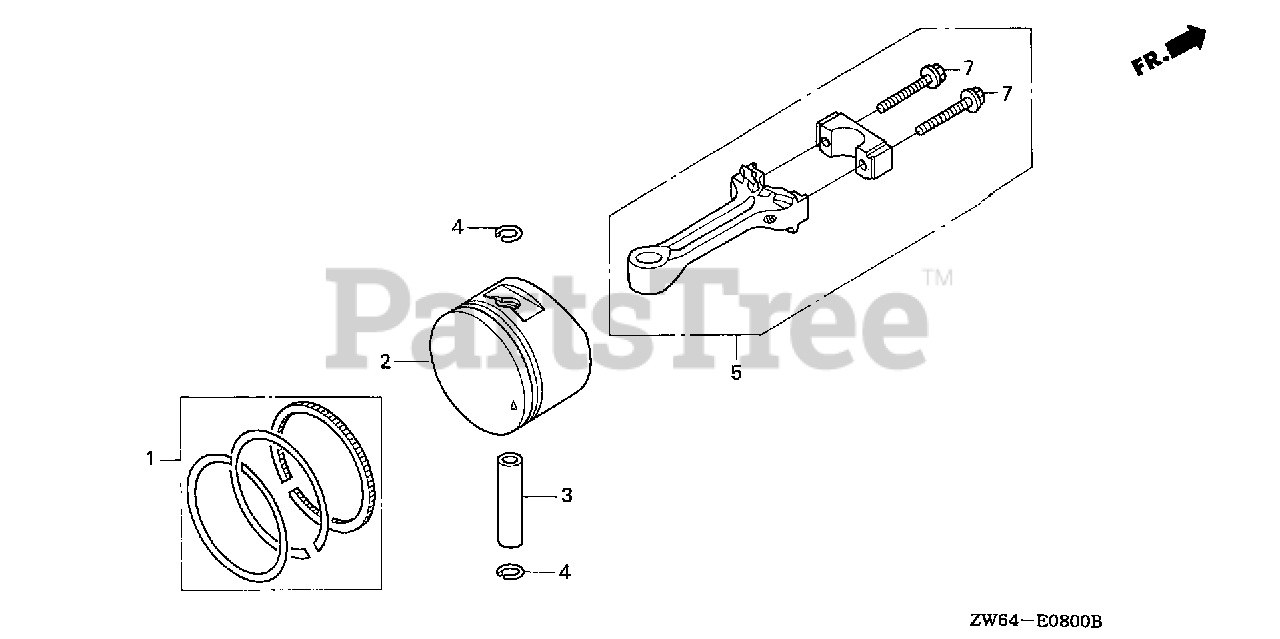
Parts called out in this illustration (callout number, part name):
1	RING SET, PISTON (STD)
2	PISTON (STD)
3	PIN, PISTON
4	CLIP, PISTON PIN (10MM)
5	ROD ASSY., CONNECTING
7	BOLT, CONNECTING ROD
